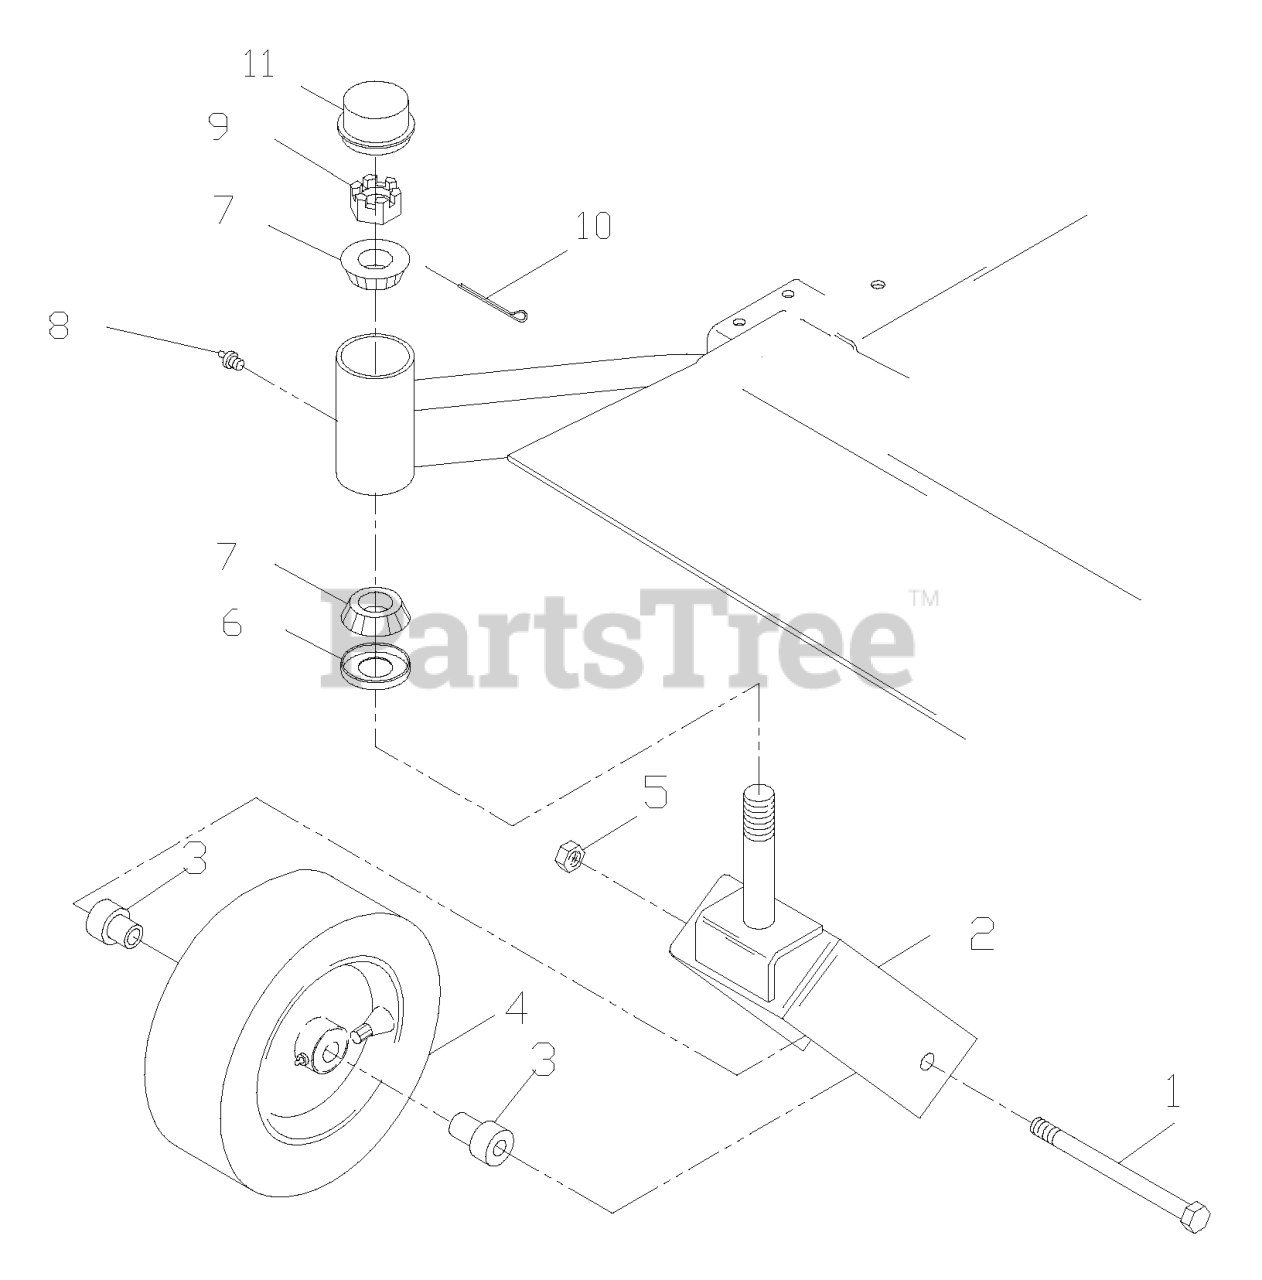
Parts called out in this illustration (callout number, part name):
1	HEX SCREW 1/2-13 X 9.5 GR5
2	CASTOR YOKE ORANGE
3	AXLE SPACER
4	FRONT TIRE ASSY
4	TIRE - SMOOTH 13X6.50-6
4	TAPERED BEARING W/RACE
4	VALVE STEM TR-412
5	NUT 1/2-13 HEX NYLOC ZD
7	BEARING W/CUP
8	ZERK
9	NUT 1"C HEX SLOTTED
10	COTTER PIN 1/8 X 2
11	GREASE CAP
